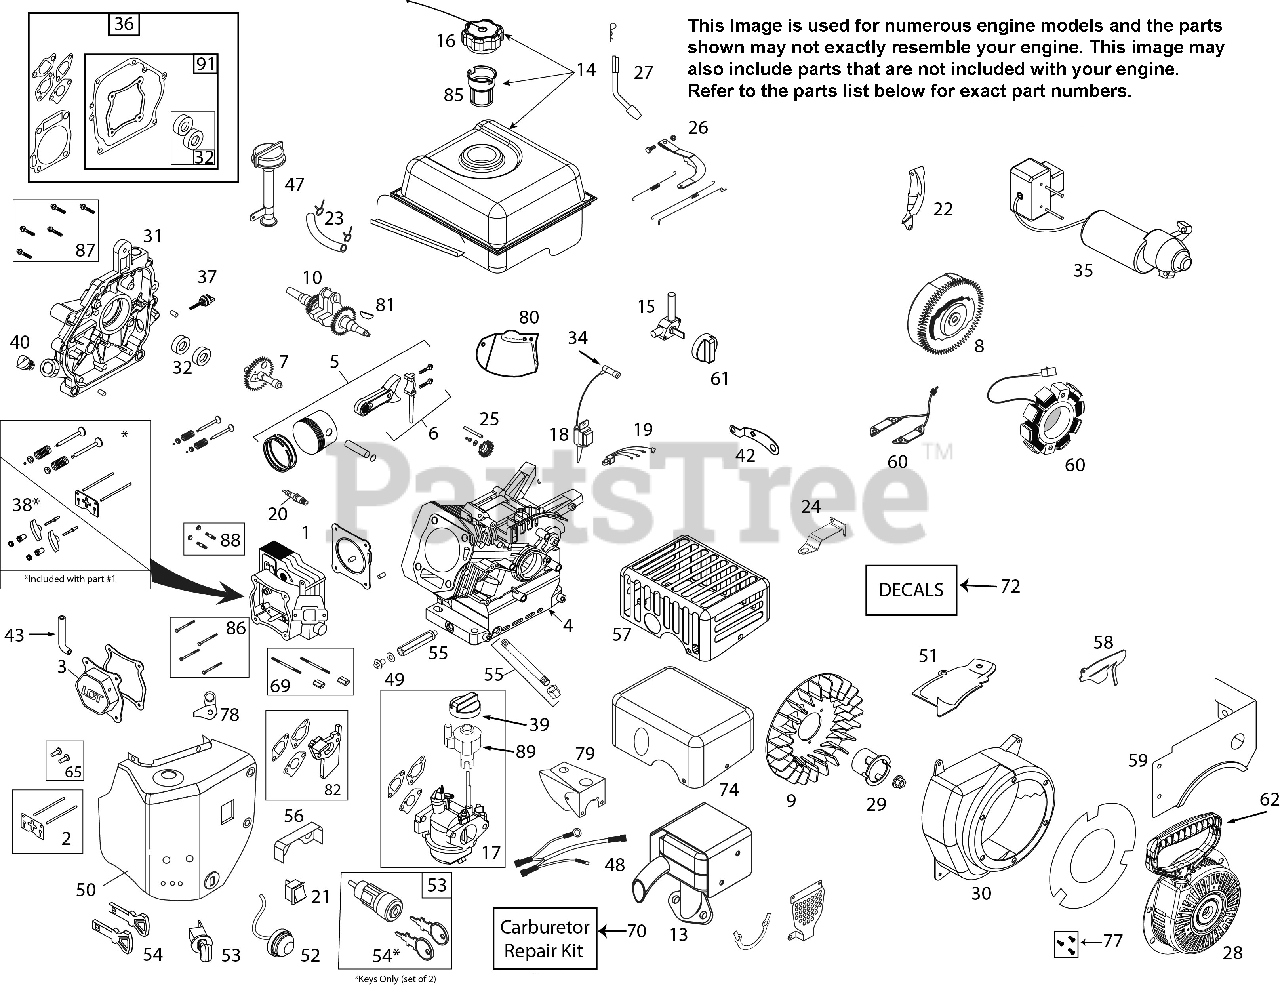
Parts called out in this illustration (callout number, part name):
1	CYLINDER HEAD ASSY(W/GASKET)
2	PUSH ROD & PLATE KIT (W/GSKT)
3	VALVE COVER (W/GASKET)
4	CYLINDER (FRONT OIL DRAIN)
5	PISTON & ROD ASSEMBLY
7	CAMSHAFT - MCR (W/GASKET)
8	FLYWHEEL - ELECTRIC START
9	COOLING FAN - FLYWHEEL
10	CRANKSHAFT (#17 KEYED)
13	MUFFLER ASSEMBLY
14	FUEL TANK ASM (MATTE BLACK)
15	FUEL TANK ON/OFF VALVE
16	CAP, FUEL TANK BLACK
17	CARBURETOR W/IDL DN-CTRL-GSKTS
18	IGNITION COIL (CDI) (STANDARD)
20	SPARK PLUG - PLATINUM
21	ON/OFF SWITCH - ROCKER (RED)
22	SHIELD - FLYWHEEL (ELECTRIC)
23	FUEL HOSE KIT 1/4-318MM
24	SPEED CONTROL BRACKET (FIXED)
25	GOVERNOR GEAR ASSEMBLY
26	GOVERNOR ARM & LINK KIT
27	GOVERNOR ARM PADDLE
28	RECOIL STARTER ASSY RND-BLACK
29	STARTER CUP RND STYLE STARTER
30	BLOWER HOUSING (GLS BLACK)
31	CRANKCASE COVER
32	OIL SEAL KIT (2 PCS)
34	SPARK PLUG BOOT (W/MTL SHIELD)
35	120V ELECTRIC STARTER
36	ENGINE GASKET KIT
38	ROCKER ARM KIT (W/GASKET)
39	CHOKE CONTROL KNOB (RED)
40	NON-REMOVABLE PLASTIC PLUG
43	BREATHER TUBE
47	HIGH OIL-FILL TUBE/DIPSTICK
48	WIRE HARNESS
49	OIL DRAIN PLUG (W/WASHER)
50	HEATER BOX, MATTE BLACK, 254CC
51	CYLINDER SHIELD - 254CC SNOW
52	PRIMER BULB WITH HOSE-SNOW (RED)
53	KEY SWITCH, STOP-RUN (W/KEYS)
54	KEY, TURN LCT (2/PACKAGE)
55	FRONT OIL DRN PIPE & NUT ASSY
56	CARBURETOR VAPOR SHIELD
58	SHIELD - GOVERNOR LINKAGE
59	FUEL TANK SKIRT (MATTE BLACK)
60	CHARGING COIL (60-WATT AC)
61	FUEL CONTROL KNOB (RED)
62	STARTER GRIP-SNOW (DELUXE)
65	TAPPET KIT (SET OF 2)
69	CARBURETOR STUDS & COUPLNG KIT
70	CARBURETOR REPAIR KIT
72	ARIENS 254 (ALL) SNW DCL KIT
74	MUFFLER HEAT SHIELD COVER
77	RECOIL BOLT KIT
79	CARBURETOR COVER
80	SHIELD GOVERNOR LINK
81	WOODRUFF FLYWHEEL KEY 5-PACK
82	CARBURETOR SPACER
85	FUEL TANK STRAINER
86	HEAD BLT KIT 136-179-208-254CC
87	CC COVER BLT KIT 179-208-254CC
88	MUFFLER MTG STUD KIT
89	SPEED CONTROL KNOB
91	CRANKCASE GASKET KIT(254-GEN2)
9999	HIGH ALT JET - 254CC L15 CARB
9999	HARDWARE KIT (4 M6X10 FLG BLT)
